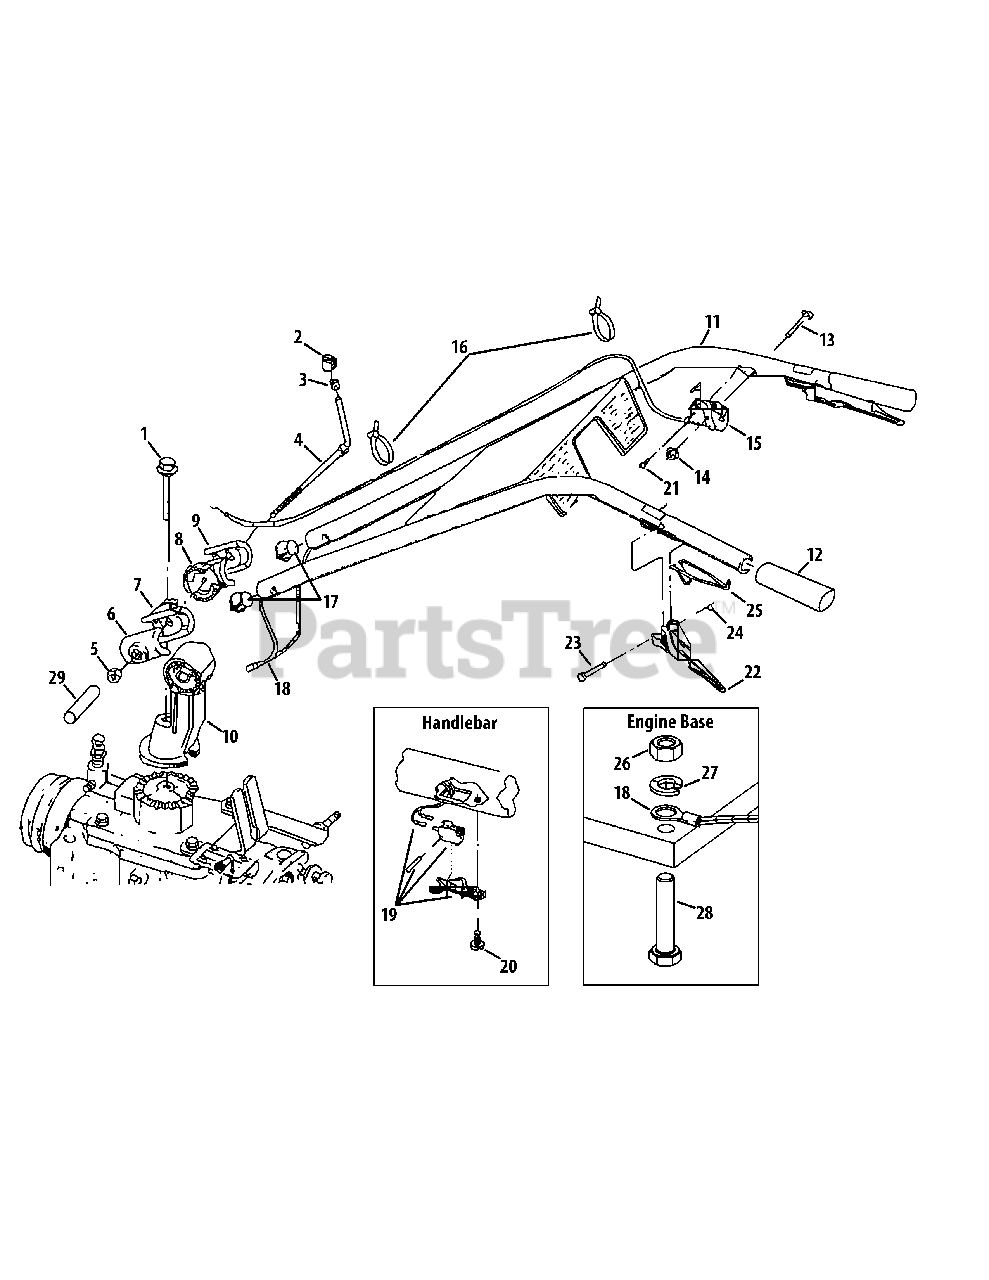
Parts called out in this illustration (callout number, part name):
1	Hex Bolt, 1/2"-13 x 3-1/2"
2	Handlebar Height Adjustment Knob
3	Retaining Ring
4	Handlebar Height Adjustment Stud
5	Hex Nut, 1/2"-13
6	Handlebar Hgt, Adj. Clamp (LT)
7	Handlebar Hgt. Adj. Ratchet (LT)
8	Handlebar Hgt. Adj. Ratchet (RT)
9	Handlebar Hgt. Adj. Clamp (RT)
10	Handlebar Mounting Base
12	Handlebars Grip
13	Curved Head Bolt, 1/4"-20 x 2"
14	Hex Nut, 1/4"-20
15	Throttle Control & Cable, 66"
16	Plastic Tie
17	Wire Harness Retainer Plug
18	Handlebar Wire Harness Assembly
19	Switch Assembly
20	Pan Head Screw, #10-16 x 1/2"
21	Phillips Head Screw, 10-32 x 1/2"
22	Operator Presence Control Lever
23	Pivot Pin
24	Retaining Ring
25	Return Spring
26	Hex Nut, 5/16"-18
27	Washer, 5/16"
28	Hex Head Screw, 5/16"-18 x 1.5
